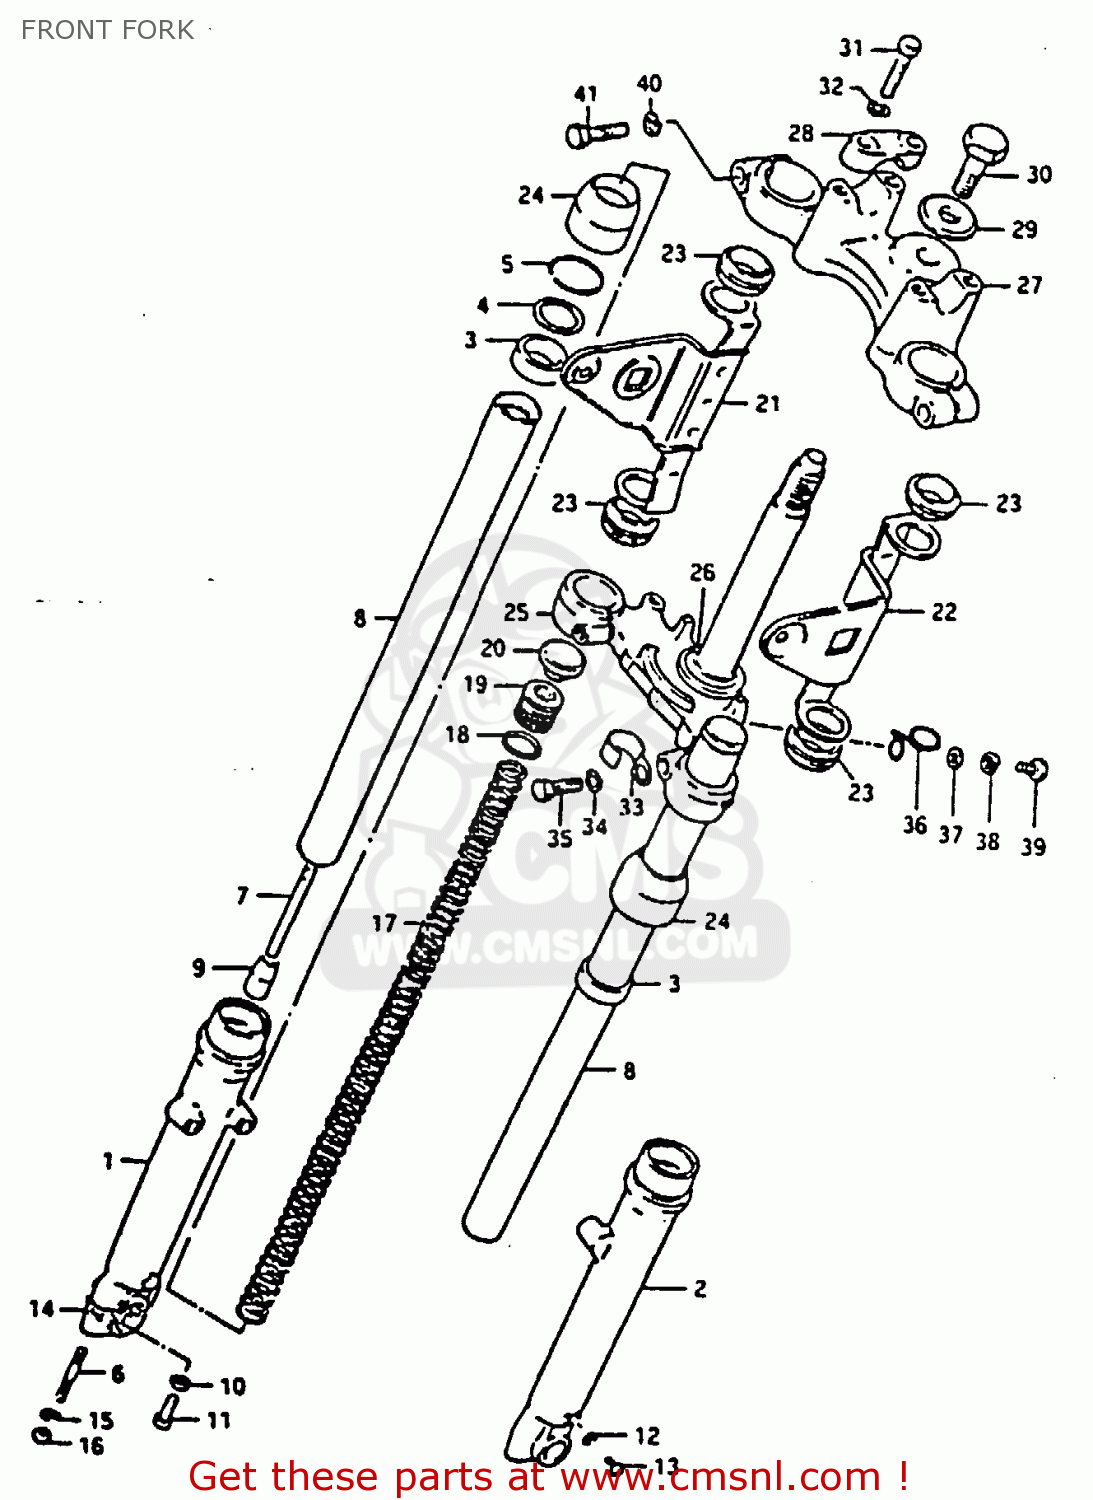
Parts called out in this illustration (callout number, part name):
1	TUBE,FORK,OUTER,RIGHT
2	TUBE,FORK,LEFT,OUTER
3	OIL SEAL,FRONT FORK
4	WASHER,FRONT FORK
5	RING,SNAP
6	STUD BOLT
7	CYLINDER,FRONT FORK
8	TUBE,FORK,INNER
9	PIECE,OIL LOCK
10	GASKET (NAS)
11	BOLT,FORK CYLINDER(10X25)
12	GASKET,DRAIN,PLUG (NAS)
13	SCREW
14	HOLDER,AXLE
15	LOCK WASHER
16	NUT (8MM)
17	SPRING
18	O RING
19	CAP
20	CAP,FR FORK
21	BRACKET,HEADLAMP HOUSING
22	BRACKET,HEADLAMP,LEFT
23	GASKET (NAS)
24	SEAL,DUST
25	STEM, STEERING (BLACK)
26	RACE,STEERING OUTER LWR
27	HEAD,STEERING STEM
28	HOLDER,HANDLE(BLACK)
29	WASHER,STEM HEAD(10.5X30X3.2)
30	BOLT,FORK INNER TUBE
31	BOLT
32	LOCK WASHER
33	CLIP
34	WASHER,LOCK 12
35	BOLT,FR FORK LWR(12X33)
36	CLIP
37	WASHER
38	LOCK WASHER
39	SCREW 6X12
40	LOCK WASHER
41	BOLT,FORK INNER TUBE F
